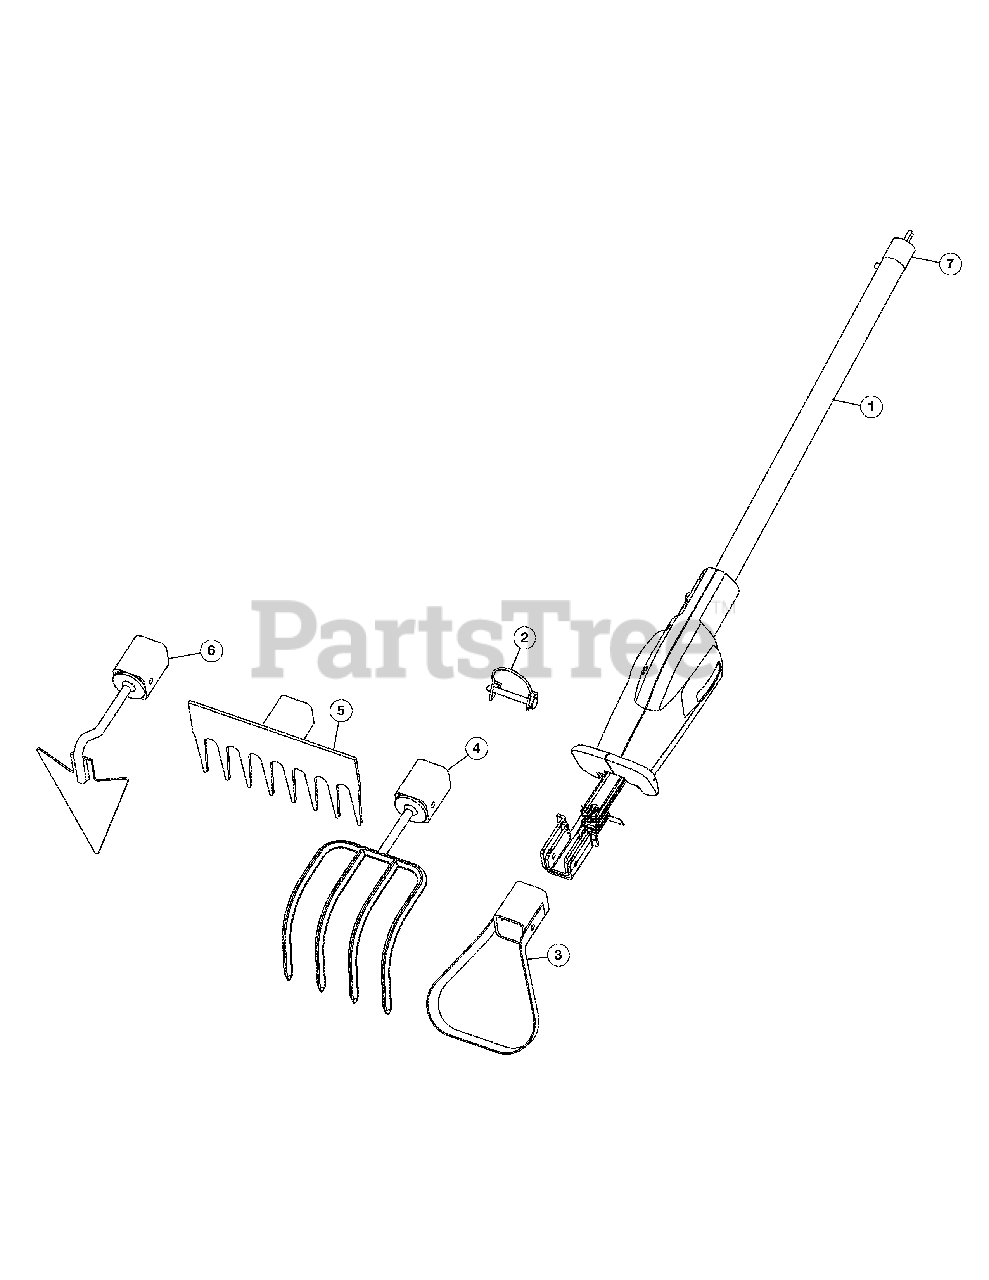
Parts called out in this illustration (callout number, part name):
1	Boom Assembly
2	Hinge Pin
3	Action Hoe
4	Cultivator
6	Warren Hoe
7	Hanger
